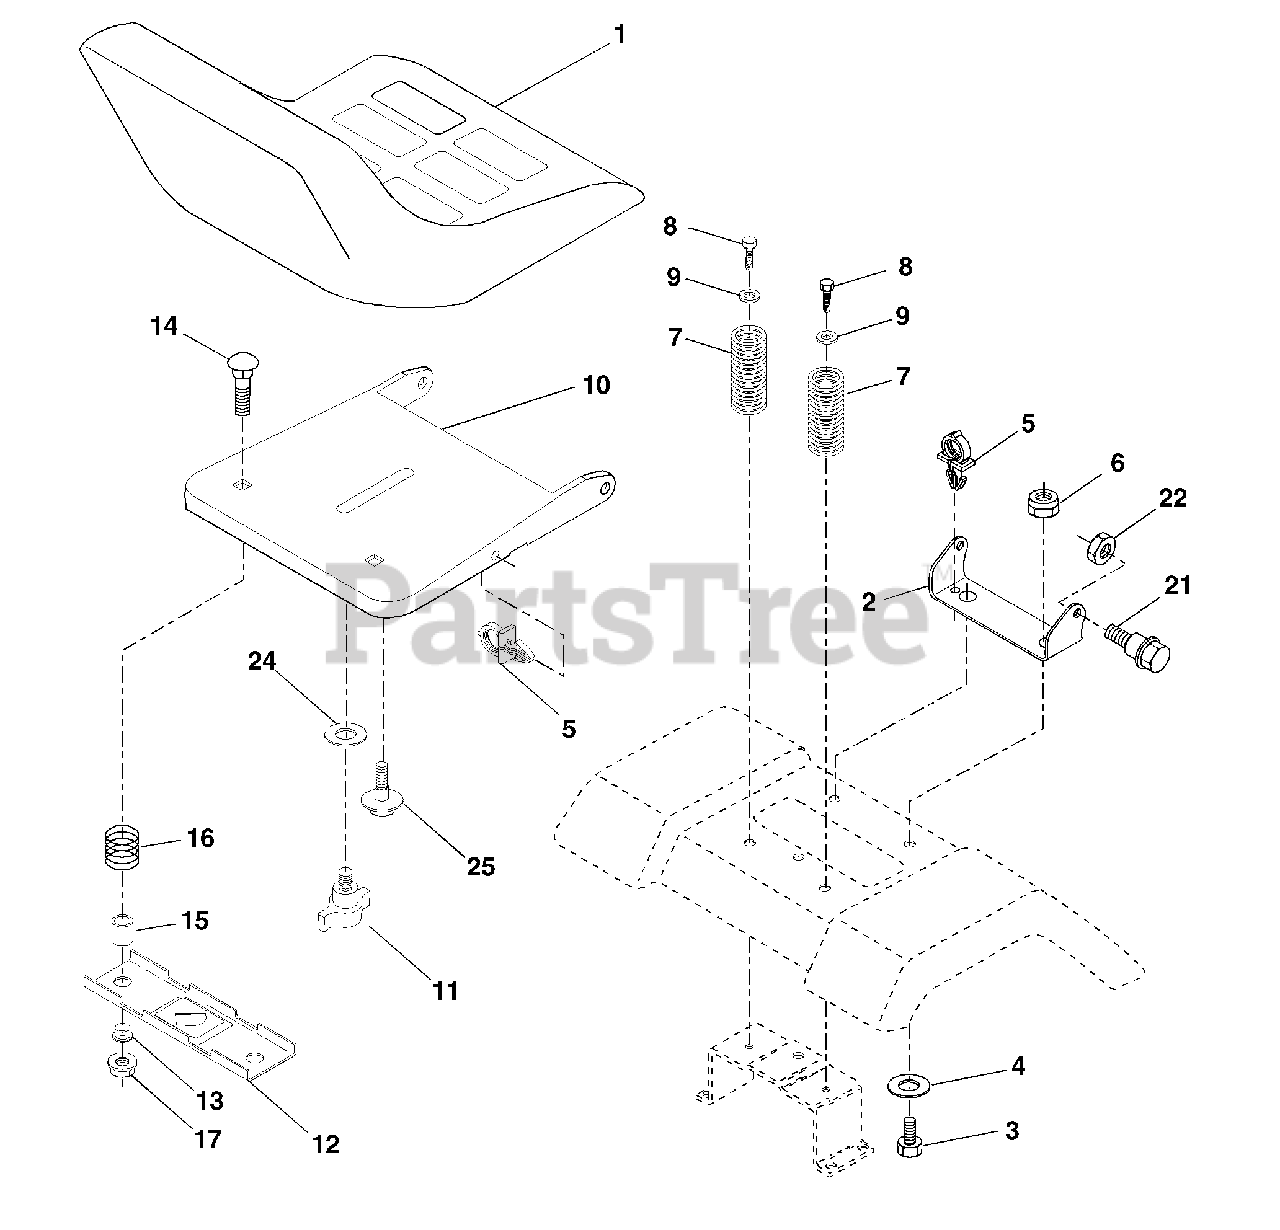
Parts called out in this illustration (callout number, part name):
1	Seat
2	Bracket Pivot Seat 8 720
3	Bolt Fin Hex 3/8-16 x 1
4	Washer Flat 13/32 x 1.0 x 10 Ga.
5	Clip Push-In
6	Nut Hex w/Ins. 3/8-16 Unc
7	Spring Seat Cprsn 2 250 Blk Zi
8	Screw 3/8-16 x 1
9	Washer 13/32 x 1.0 x 14 Ga.
10	Pan Seat
11	Knob Seat Adj Wingnut
12	Bracket Mounting Switch
13	Bushing Snap Blk Nyl 50 Id
14	Bolt Rdhd Sqnk 1/4-20x1-1/2
15	Spacer Split 28 x .88 Zinc
16	Spring Cprsn Plate
17	Nut Lock 1/4 Lge Flg Gr 5 Zinc
21	Bolt Shoulder 5/16-18 Unc
22	Nut Hex Lock W/Ins 5/16-18
24	Washer 17/32 X 1 -3/16 X 12 Ga.
25	Bolt Shoulder 5/16-18 X 62
